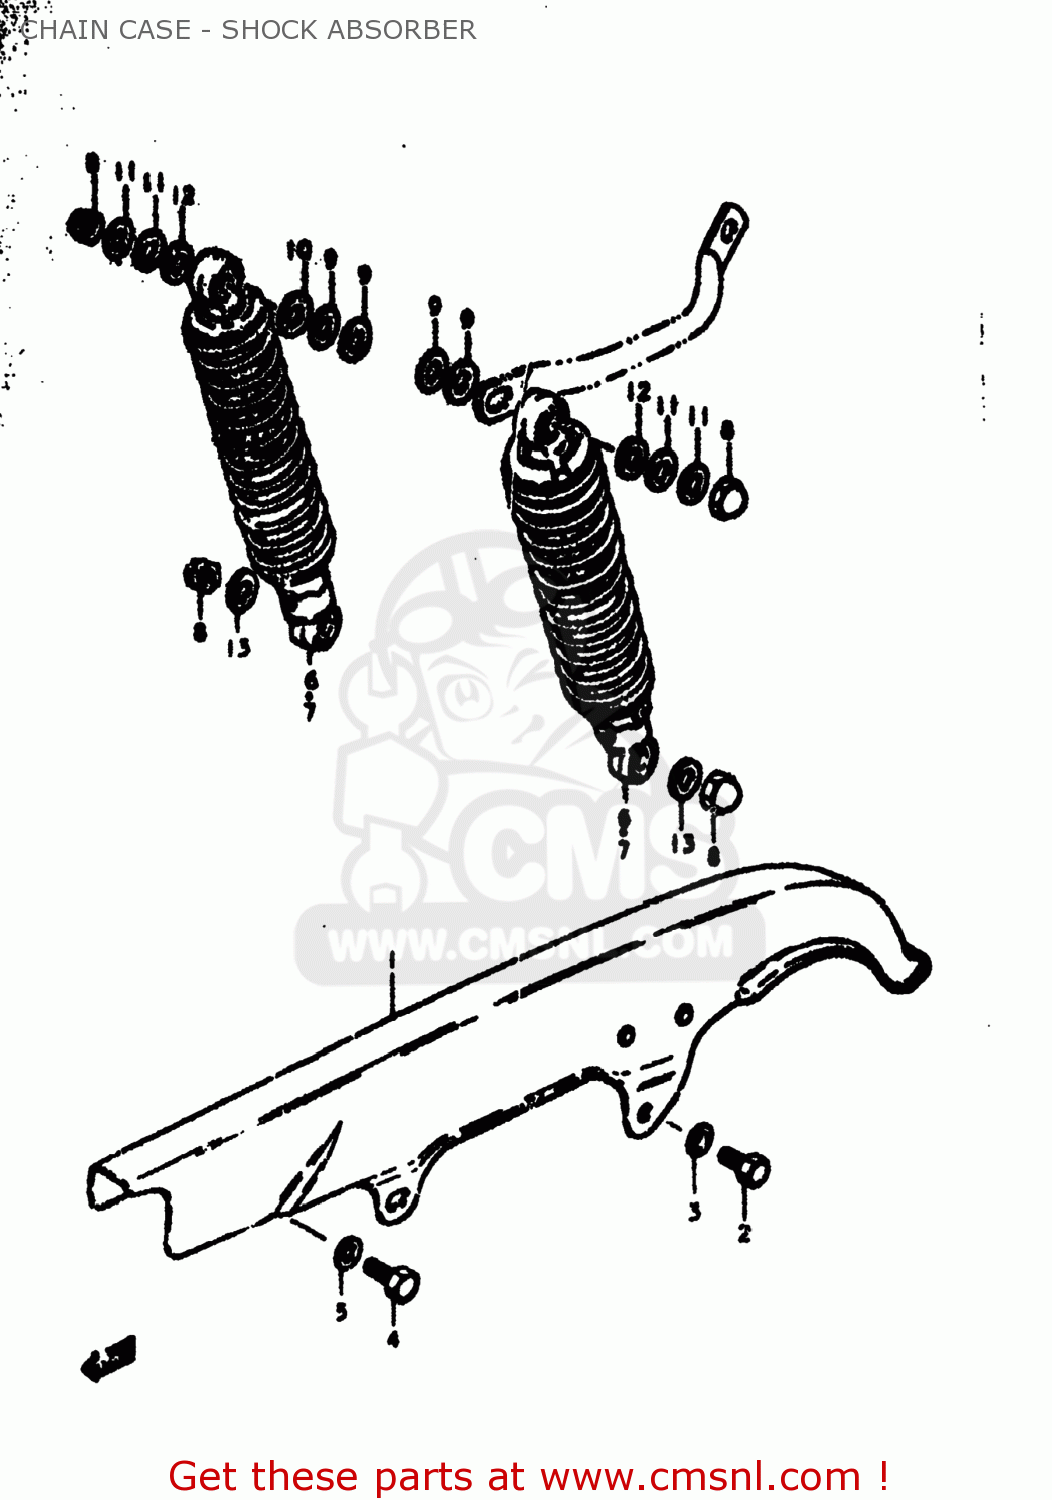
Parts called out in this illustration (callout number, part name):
1	CASE,CHAIN
2	BOLT(6X8)
3	WASHER
4	BOLT
5	WASHER(6.5X18X1)
6	ABSORBER ASSEMBLY,REAR SHOCK
7	ABSORBER ASSEMBLY,REAR SHOCK
8	NUT, LOWER LH
9	WASHER
10	WASHER (12.5X24X3.2)
11	WASHER
12	WASHER(10.5X24X3.2)
13	WASHER
